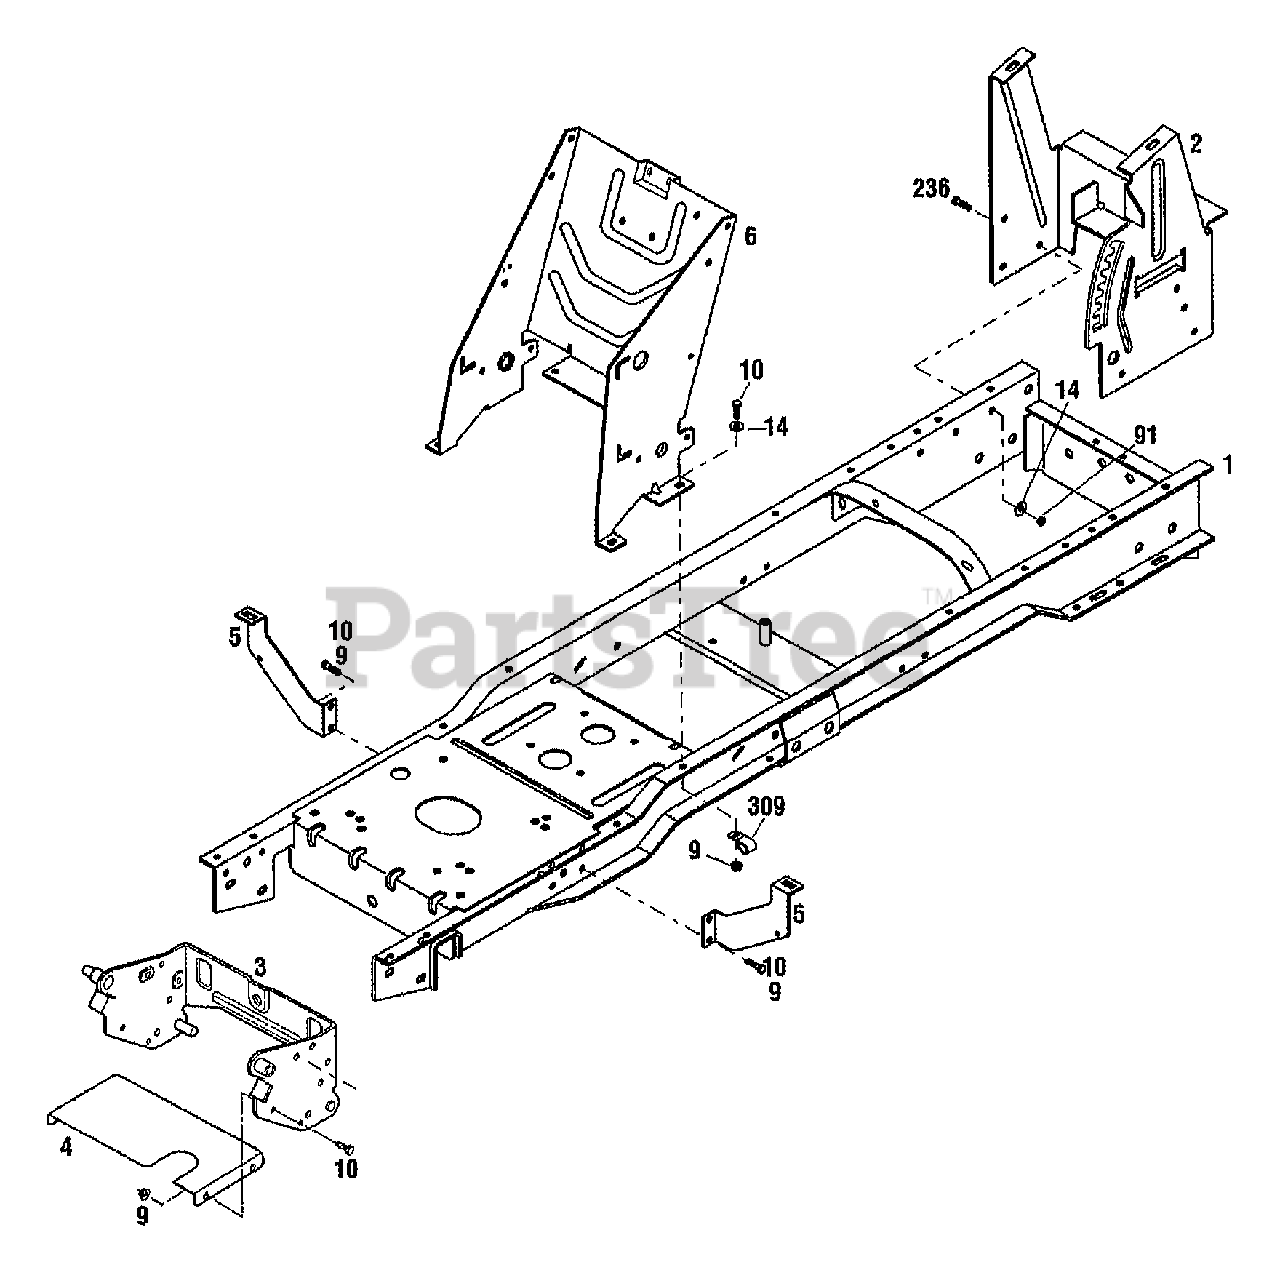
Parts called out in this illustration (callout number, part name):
2	SUPPORT-REAR TANK
3	ASSM-ATTACH BRACKET
4	SHIELD-HEAT
5	SUPPORT-FENDER
6	SUPPORT-CONSOLE
9	NUT-HFLK 5/16-18 ZP
10	SCR-HHC 5/16-18X.75 GR 5 ZP
14	WASHER-FLAT 5/16 SAE
91	NUT-TOP/LK 5/16-18 ZP
236	SCR-HFLK 5/16-18X.75 ZP
309	CLIP-J
